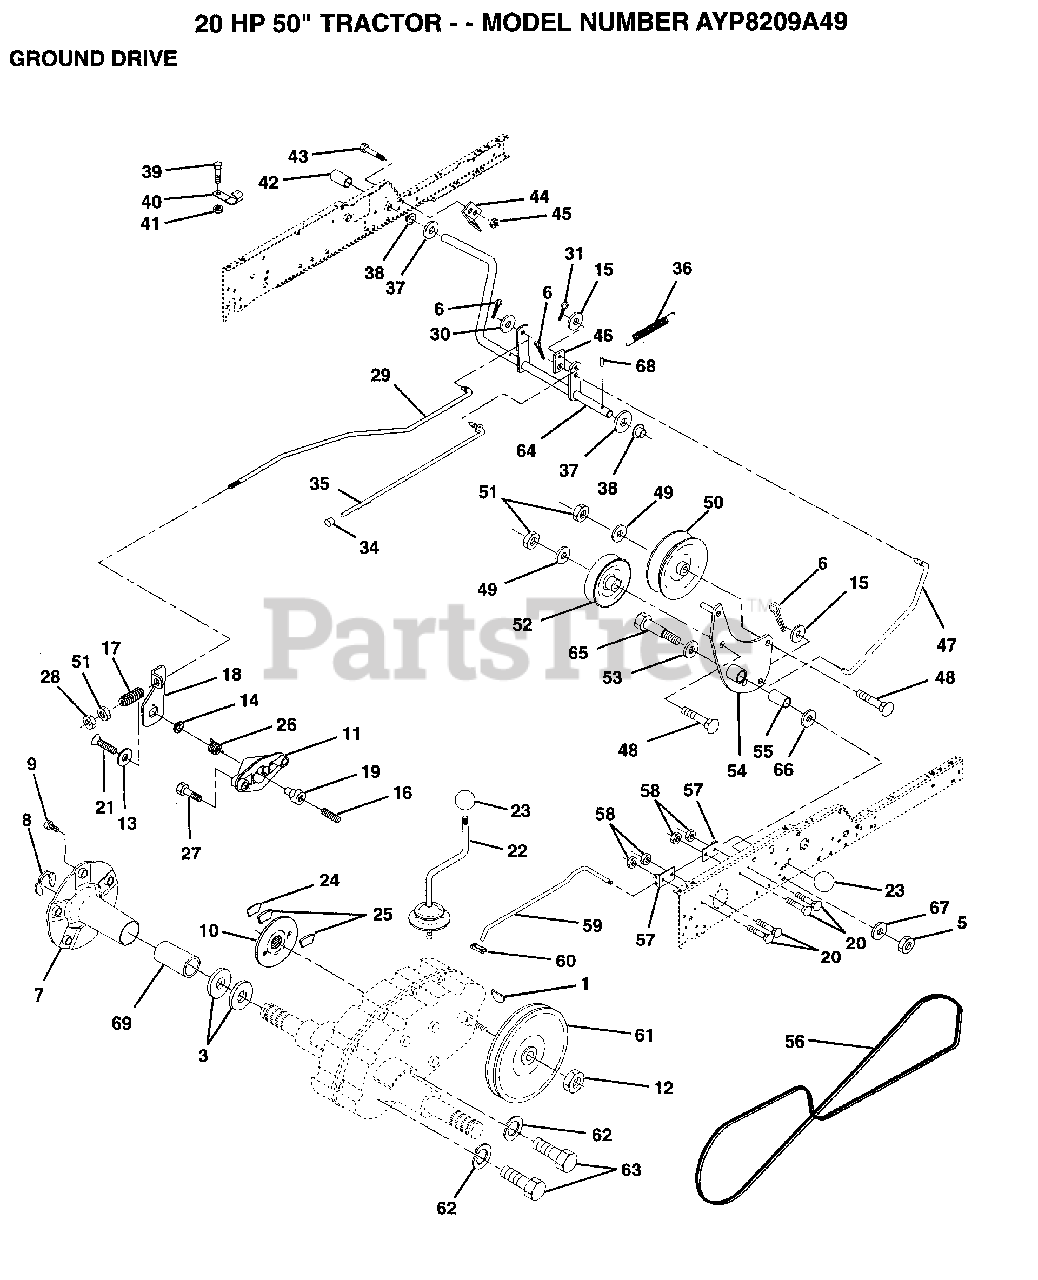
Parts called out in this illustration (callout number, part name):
3	WASHER T
6	COTTER PIN
8	KLIP RING
9	BOLT.HUB.WHL.REAR
11	YOKE BRAKE DISC
12	NUT STD
13	WASHER SPECIAL
14	BUSHING LEVER BKT
15	WASHER
16	SCREW SET 1/4-20
17	"SPRING,ROD BRAKE"
18	LEVER BRAKE GT
19	CAM BRAKE DISC GT
20	BOLT
21	SCREW SET 1/4-20
22	GEAR SHFT LVR T
23	KNOB
24	SUPPORT PUCK BRKE
25	PUCK BRAKE TOP
26	SPRING RET BRAKE
27	SCREW HX WASH
28	NUT
29	ROD BRAKE ZINC GT
30	WASHER
35	ROD BRAKE PART GT
37	WASHER
38	NYLINER T
39	SCREW
40	ACT-SWITCH T
42	PEDAL COVER T
43	BOLT LT
44	BRKT SWITCH GT
45	NUT
46	RETAINER SPRING
47	ROD.CLUTCH
48	BOLT
49	WASHER
50	FLAT IDLER PULLEY
51	NUT
52	PULLEY.IDLER.V.GR
53	WASHER T
54	ARM.ASM.IDLER.CLU
55	"LY, BEARING"
56	BELTV.GR.DR.83.
57	ROD BRACKET GT
58	NUT
59	ROD SHIFT HI LO
60	CONNECTING LINK
62	LOCKWASHER
63	BOLT
65	AXLE BOLT
66	WASHER.HARD.BLADE
67	WASHER
68	ROLL PIN STD
69	"COVER, HUB"
